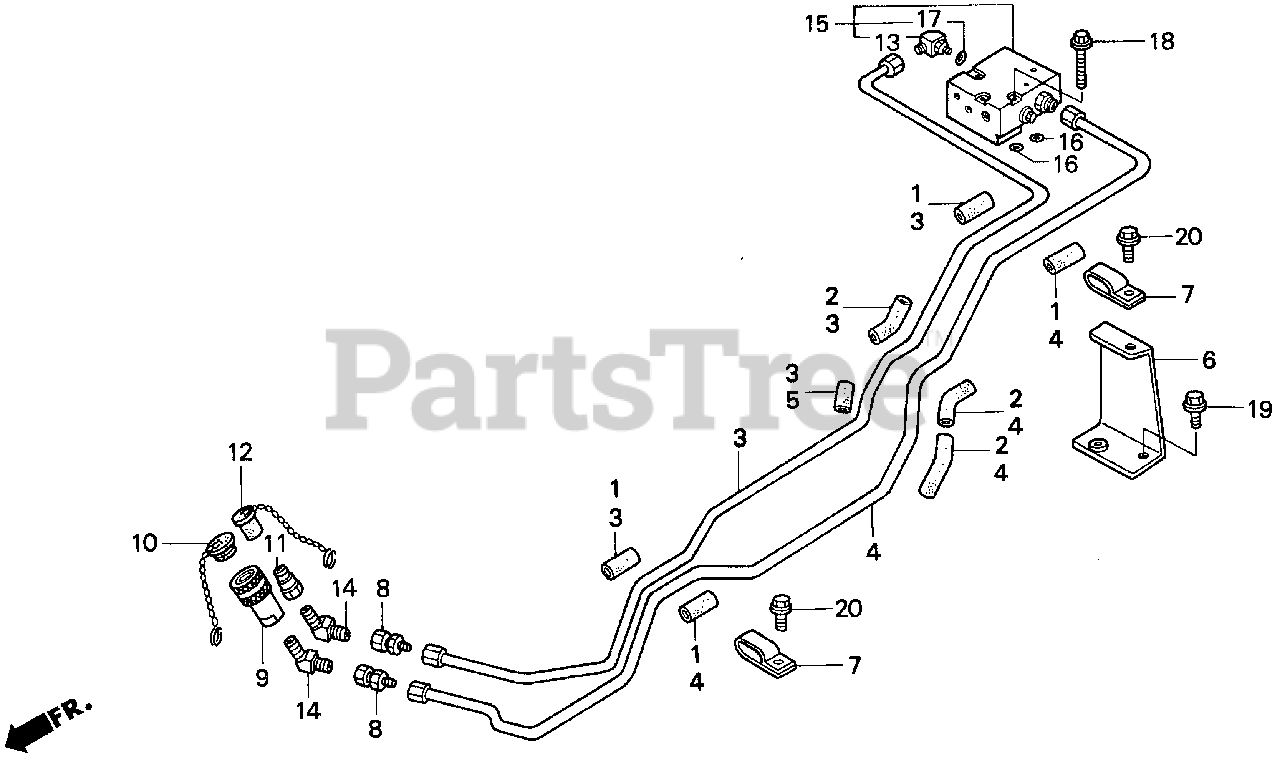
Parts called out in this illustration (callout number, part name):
1	TUBE (12X28)
2	PROTECTOR, FEED PIPE (B)
3	PIPE, RETURN
4	PIPE, DISCHARGE
5	TUBE (11.9X50)
6	BRACKET, HYDRAULIC PIPE
7	CLAMP, HYDRAULIC PIPE
8	JOINT, CONNECT (RC3/8)
9	COUPLING, FEMALE (3/8)
10	PLUG, COUPLING (3/8)
11	COUPLING, MALE (3/8)
12	CAP, COUPLING (3/8)
13	JOINT, JOB ELBOW (3/8)
14	JOINT, ELBOW (3/8 R-NPT)
15	VALVE ASSY., HYDRAULIC OUTPUT
16	O-RING (11.8X2.4)
17	O-RING (13.8X2.4) (NOK)
18	BOLT, FLANGE (6X55)
19	BOLT, FLANGE (8X22)
20	BOLT, FLANGE (6X12)
